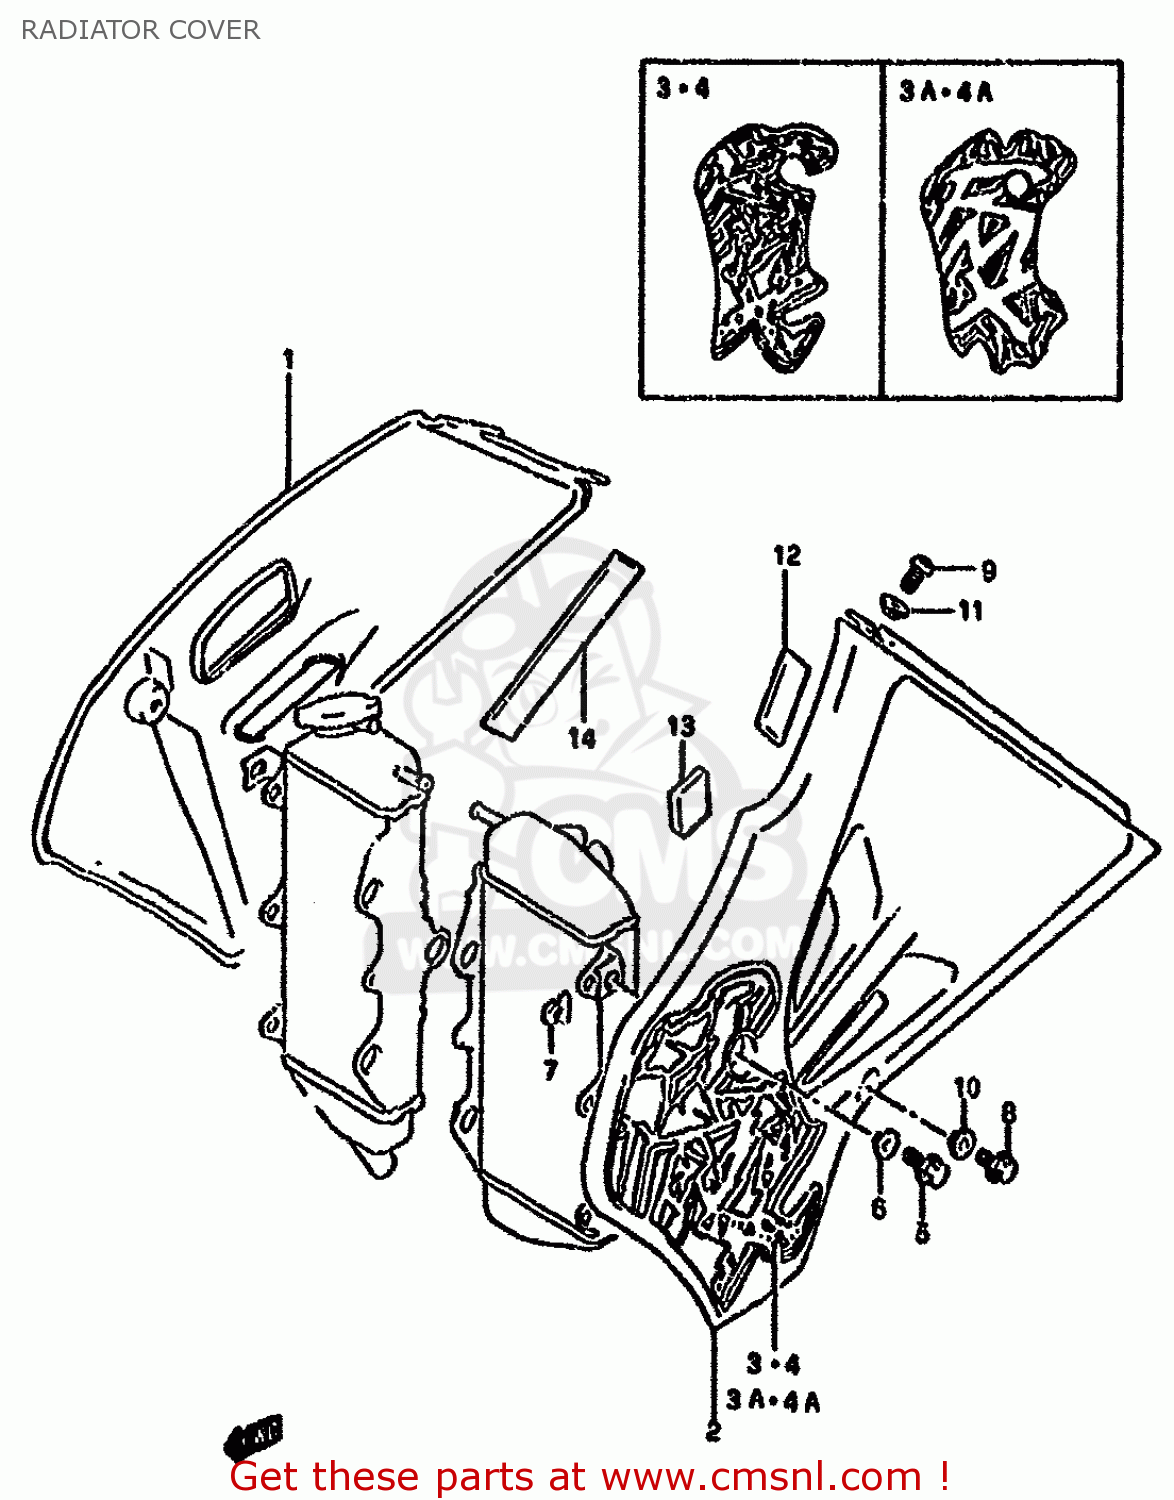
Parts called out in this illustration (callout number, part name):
1	COVER,RADIATOR,R(YELLOW)
2	COVER,RADIATOR,L(YELLOW)
3	EMBLEM,RADIATOR COVER,R
3A	EMBLEM,RADIATOR COVER,R
4	EMBLEM,RADIATOR COVER,L
4A	EMBLEM,RADIATOR COVER LH
5	BOLT
6	WASHER(6.5X16X1.2)
7	PLATE,RADIATOR COVER FITING
8	BOLT
9	SCREW 6X12
10	WASHER(6.5X16X1.2)
11	WASHER(6.5X18X1)
12	CUSHION,RADIATOR COVER
13	CUSHION,RADIATOR COVER FR
14	CUSHION,COVER SIDE
